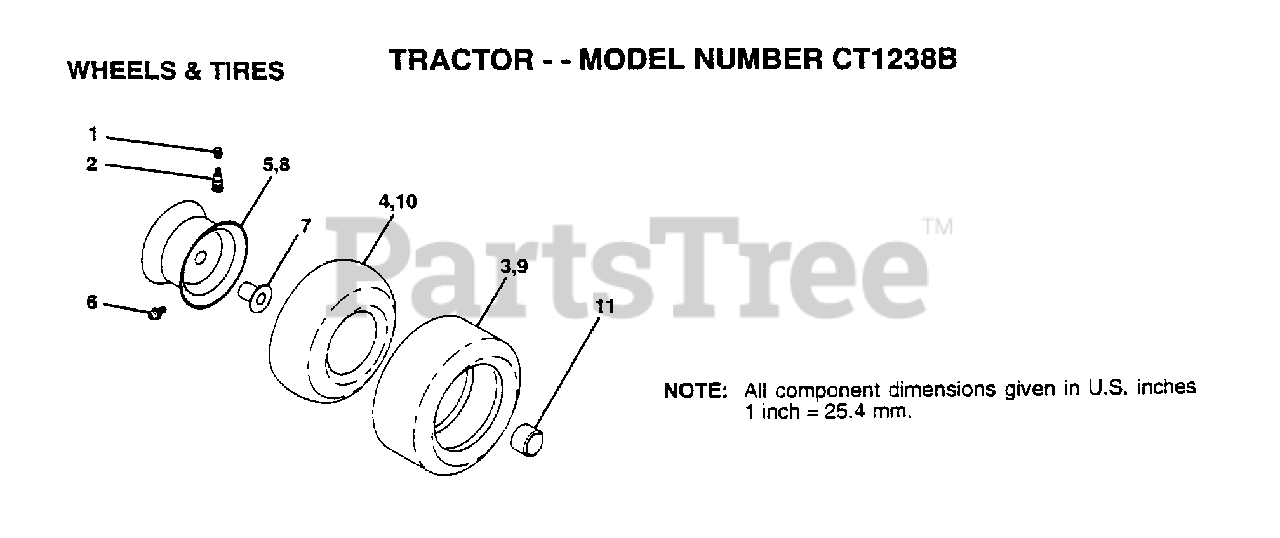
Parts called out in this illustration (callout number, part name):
1	VALVE CAP
2	VALVE STEM LT
4	TUBE.5.3/4.5/6
5	"RIM ASM 6"" FRT"
6	FITTING LT
7	"FLANGE, BEARING"
8	"RIM AS 8"" REAR"
9	TIRE.TS2.18X8.5
10	TUBE.18X9.5-8
11	HUB CAP
